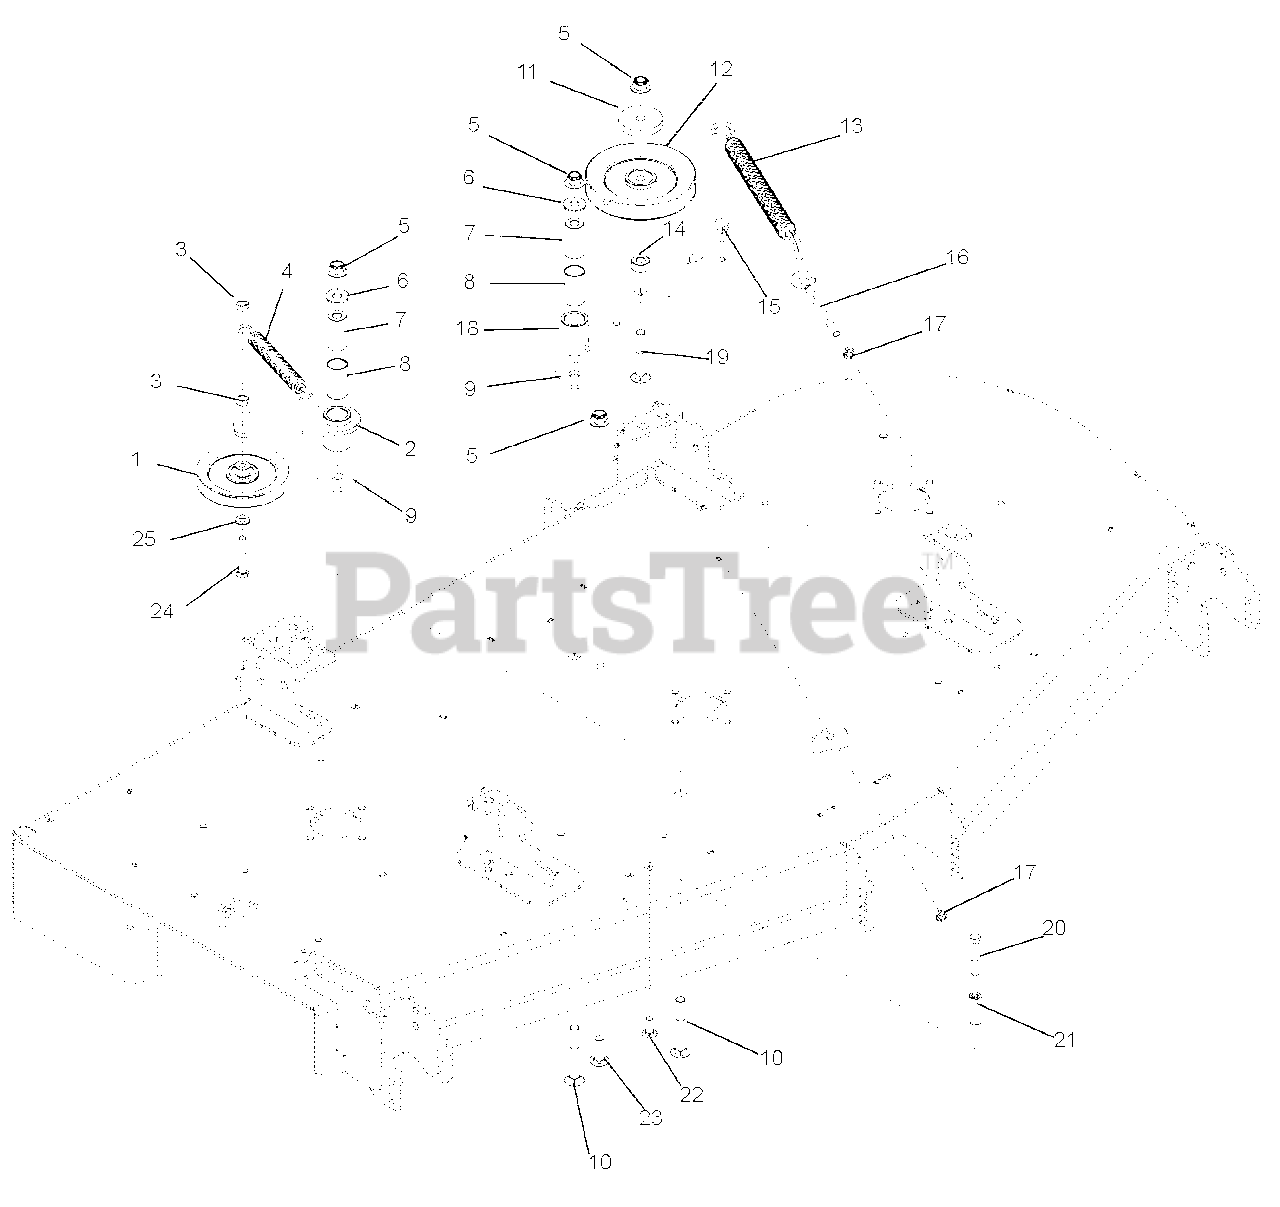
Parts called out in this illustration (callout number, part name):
1	Sheave, .38"ID x 5.00"OD V-Idler
2	Weldment, Idler Arm
3	Nut-Locking-Center .38-16
4	Spring, Extension
5	Nut-Locking-Nylon-Flange .50-13
6	Washer-Flat-Steel .563 x 1.38 x .109
7	Bushing, Spacer .505/.500 x .999/.996 x 2.05/2.03
8	Bushing, 1.00 x 1.125 x 1.936
9	Washer-Flat .640 x 1.75 x .250
10	Bolt-Round Head Square Neck .50-13 x 3.50 Grade 5
11	Cap, Idler Bearing Sealing
12	Sheave, .50"ID x 6.00"OD V-Idler
13	Spring, Extension
14	Bushing, Spacer .502 x .997 x .50
15	Bolt,Shoulder EP .38-16 x .30 Hex
16	Bolt, .38-16 x 5.50 .62 Diameter Eye
17	Nut-Hex-Jam .375-16
18	Weldment, Idler Arm
19	Bolt-Round Head Square Neck .50-13 x 3.00 Grade 5
20	Bolt-Hex .38-16 x 1.75 Grade 5
21	Nut, Cupling .375-16 x 1.75
22	Bolt-Round Head Square Neck .38-16 x 1.00
23	Bolt-Round Head Square Neck .50-13 x 1.50 FULL Thread Grade 5
24	Bolt-Hex .38-16 x 2.25 Grade 5
25	Washer-Flat-Steel .406 x .812 x .065
